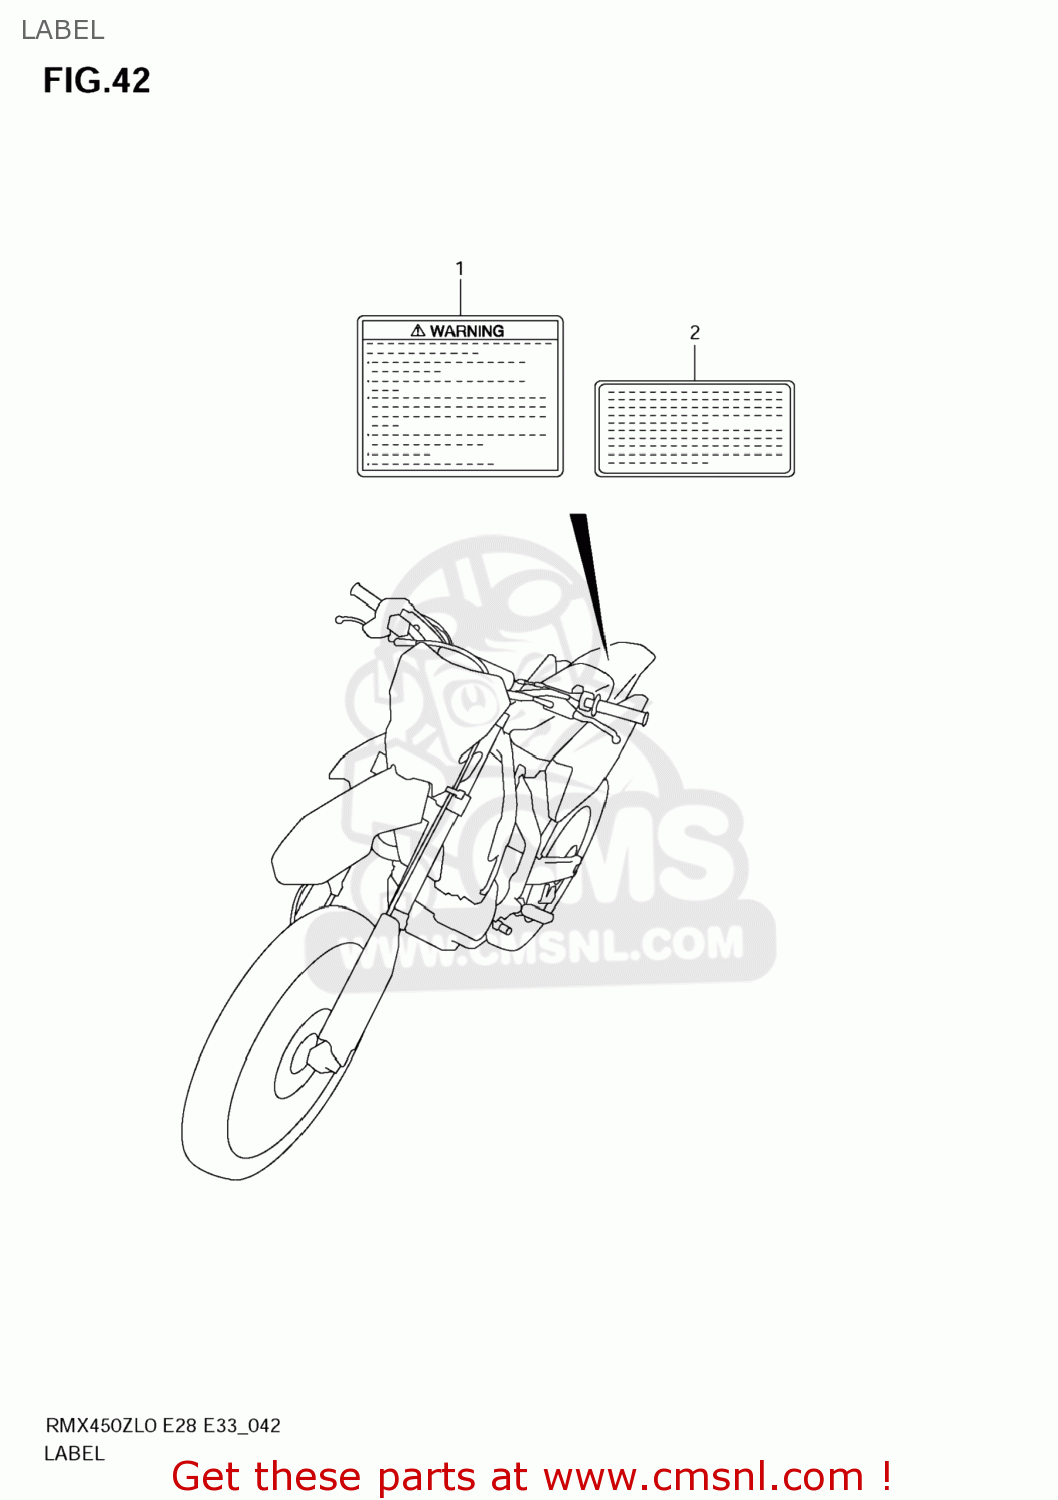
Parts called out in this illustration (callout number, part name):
1	LABEL,GENERAL WARNING
2	LABEL,MANUAL NOTICE
3	MANUAL,OWNER'S
